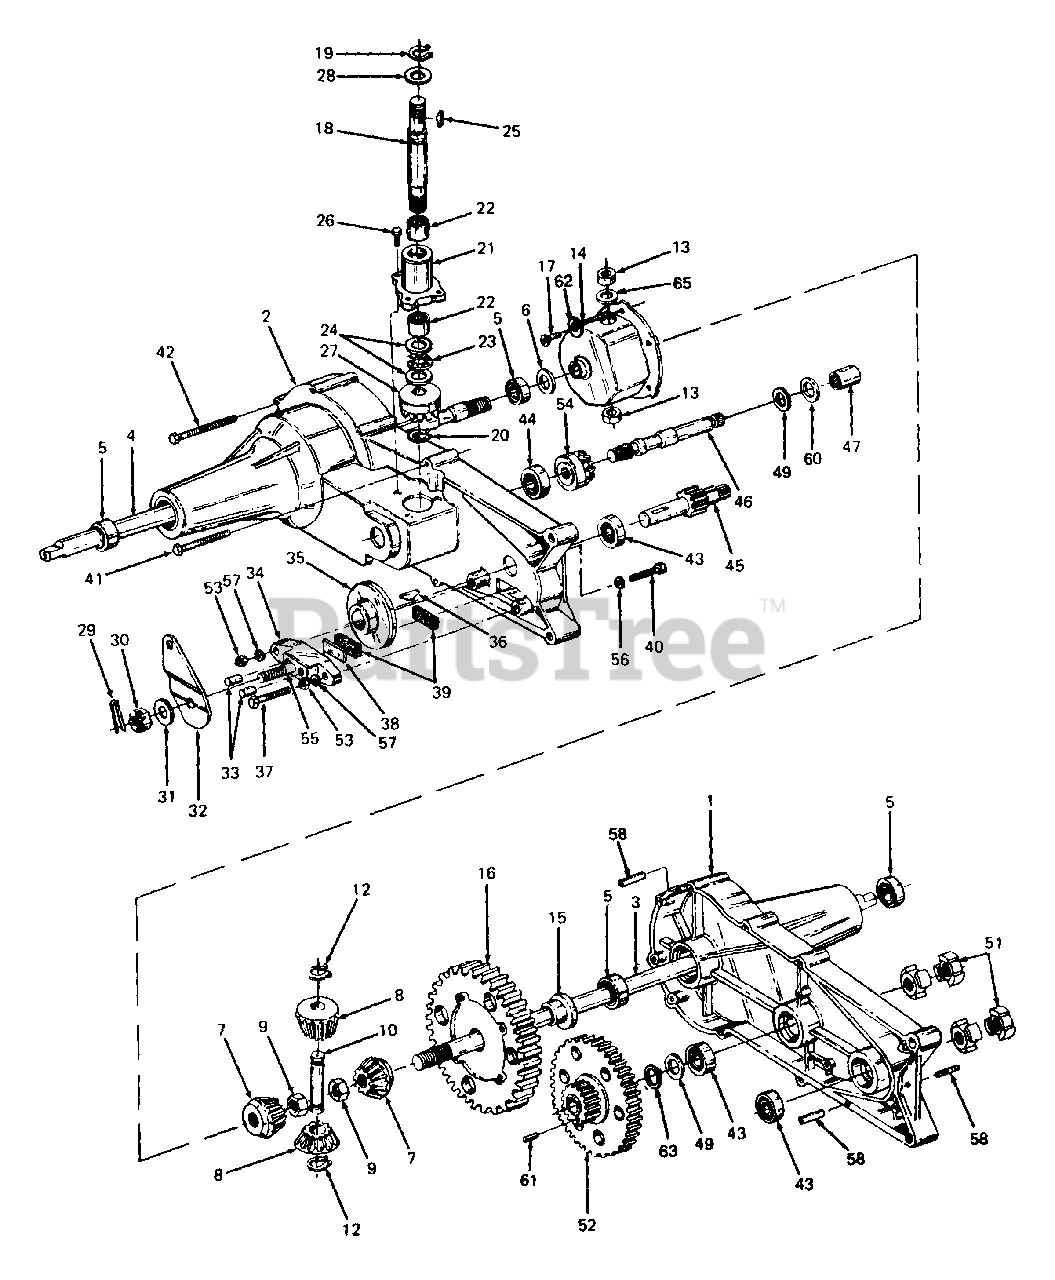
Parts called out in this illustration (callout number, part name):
1	Housing Half, L.H.
2	Housing Half, R.H.
3	Axle, L.H.
4	Axle, R.H.
5	Bearing, Ball
6	Washer, Flat, .76" x 1-1/8" x .306" Thk. Hdn.
7	Gear, Miter
8	Gear, Miter
9	Nut, Hex Jam Patch Lock, 1/2-20
10	Shaft, Cross
12	Ring, Snap
13	Bearing, Thrust
14	Housing Ass'y. Differential
15	Bearing, Flange, .75" I.D. x .587"
16	Gear, Differential, 72 Tooth
17	Torx Hd. AB-Tap Scr. 1 4 x .62" Lg.
18	Shaft, Input
19	Ring, Snap
20	Ring, Retaining, Ext. 7/16" Dia.
21	Bearing, Input Housing
22	Bearing, Needle, 5/8" I.D. x .50" Lg.
23	Bearing, Thrust
24	Washer, Flat, 5/8" I.D. x 1.12" O.D. x .030" Thk.
25	Key #4 Hi-Pro, 3/32" x 5/8" Dia. (Hdn.)
26	Screw, Hex Patch Lock, 1/4-20 x 3/4" Lg.
27	Gear, Input Pinion, 17 Tooth
28	Washer, Flat, .62" I.D. x 1.0" O.D. x .030" Thk.
29	Pin, Cotter
30	Nut, Castle, 5 16-24 Thd.
31	Washer, Flat, .343" x .88" x .062" Thk.
32	Arm, Brake Actuator
33	Pin, Actuating, 5/16" Dia.
34	Yoke, Brake
35	Disc, 8rake
36	Key, Hi-Pro, 3/16" x 5/8" Dia.
37	Screw, Hex Patch Lock, 1/4-20 x 1.5" Lg.
38	Plate, Puck
39	Puck, Brake
40	Screw, Hex Cap, 1/4-20 x 1.5" Lg.
41	Screw, Hex Self-Tap, 1/4-20 x 2.0" Lg.
42	Screw, Hex Self-Tap, 1/4-20 x 2.75" Lg.
43	Bearing, Ball
44	Bearing, Ball
45	Shaft, Pinion w/11 Tooth Gear
46	Shaft, Drive
47	Bearing, Needle
49	Washer, Flat, 5/8" x 1.12" x .060" Thk.
51	Coupling
52	Gear, Tooth 60 & 17
53	Nut, Hex Jam, 1/4-20 Thd.
54	Gear, Drive Pinion, 17 Tooth
55	Bolt, Square Hd. 5/16-24 Thd.
56	Washer, Flat, .265" x .938" x .12" Thk.
57	Washer, Lock, 1/4" I.D.
58	Pin, Roll, 3/16 Dia. x .50" Lg.
60	Bronze Thrust Brg. 5/8" I.D.
61	Dowel Pin 3/32" x 1/4"
62	Washer, Spring Lock 1/4" I.D.
63	Seal, Grease
65	Washer, Flat, .62" I.D. x 1.0" O.D. x .020" Thk.
